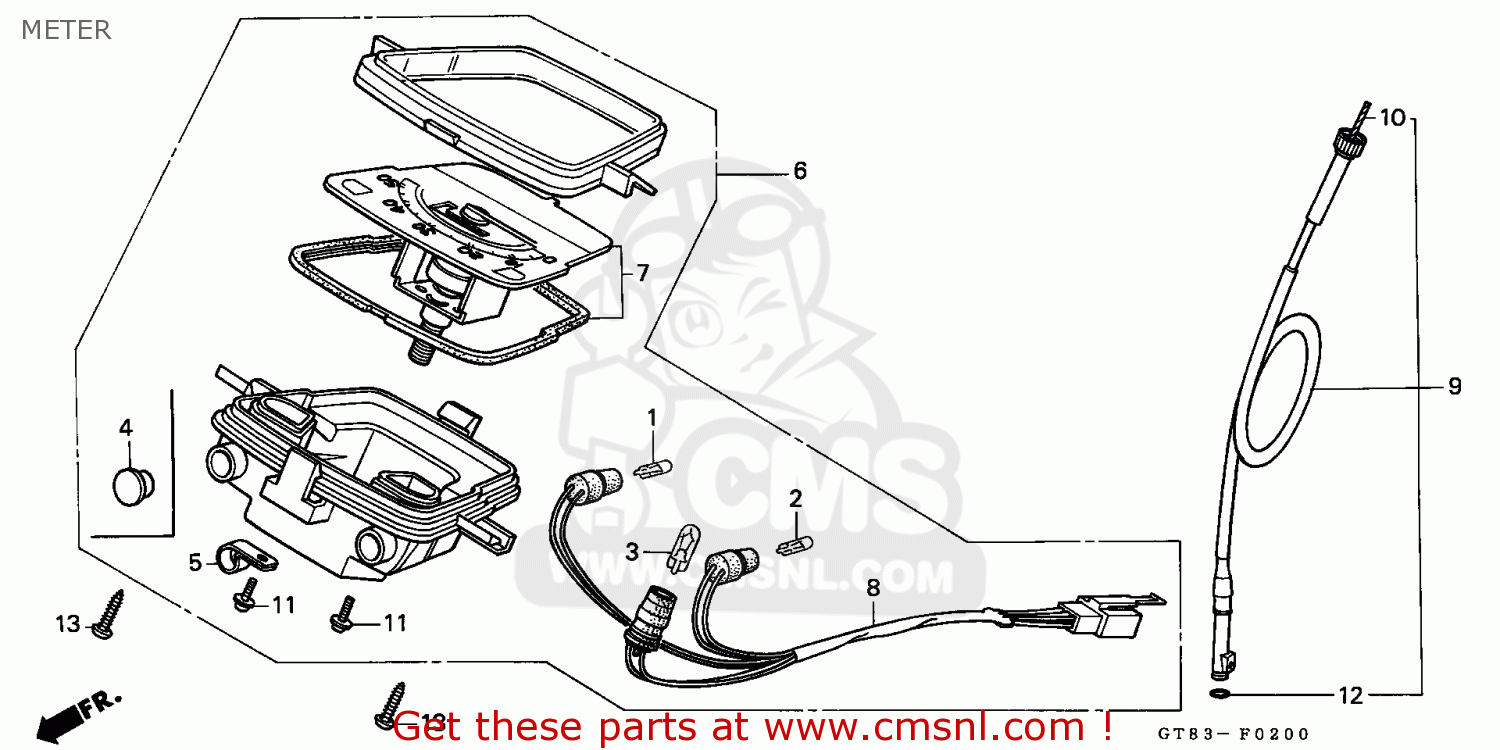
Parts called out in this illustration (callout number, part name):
3	BULB,WEDGE BASE
4	CAP
5	CLAMP
6	SPEEDOMETER ASSY.
7	SPEEDOMETER COMP.
8	SOCKET COMP.
9	CABLE COMP,SPDMT.
10	CABLE,INNER
11	SCREW,FLANGE,4X12
12	O-RING 9MM
13	SCREW,TAP.5X16
